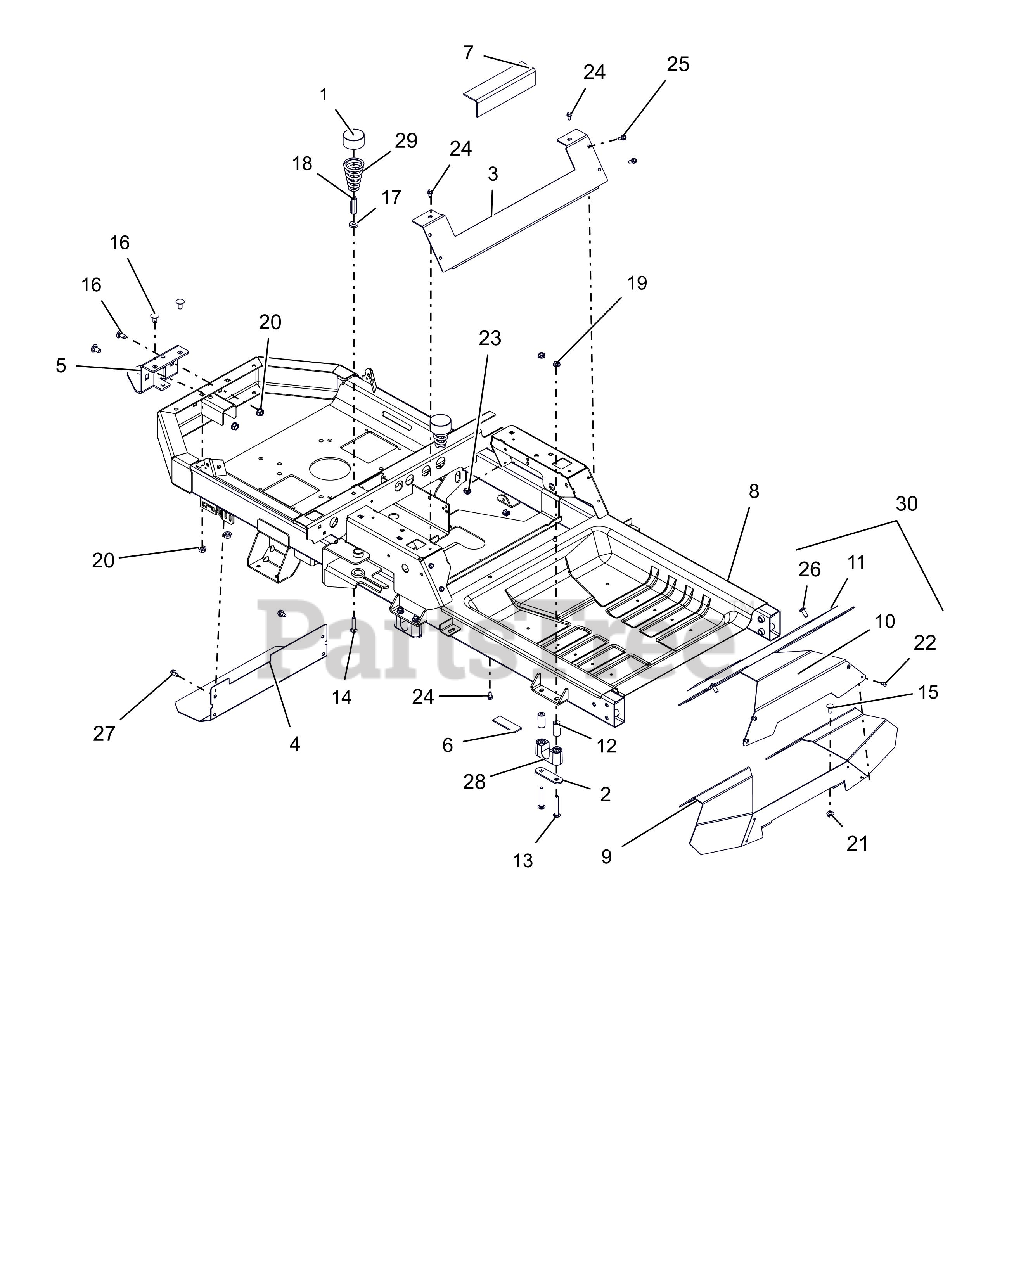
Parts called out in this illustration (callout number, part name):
1	HUB CAP
2	PLATE, BEARING SUPPORT
3	PLATE, SEAT KICK
4	HEAT, SHIELD
5	BRKT, HITCH TONGUE
6	PAD,RBR 1.0"X3.0" W/ADHESIVE
7	PAD, RUBBER-TANK
8	WLDMT, FRAME -IKON X/XL ARIENS
9	PLATE,FOOT
10	PLATE,FOOT
11	GRIP TAPE, FOOT PLATE
12	SPACER, .323 X .698 X 1.441
13	BLT-RDHDSQSHNK .31-18X2.25 YWZ
14	@BLT-RDHDSQNK .31-18X1.50 G5YZ
15	@BLT-RDHDSQNK .31-18X.75 G5YZ
16	@BLT-RDHDSQNK .38-16X.75 G5YZ
17	WSHR-FL-STL .328X.87X.179 YWZC
18	NUT, COUPLING 5/16-18 X 1 3/4
19	@NUT-LK-CTR-FLG .31-18 YZ GR F
20	@NUT-LK-TOP-FLG .38-16 YWZC
21	@NUT-LK-TOP-FLG .31-18 YWZC
22	RIVET, #66 STEEL POP PD BLACK
23	NUT RETNR .25-20
24	SCR-TAP .25-20X.50 HWH TR YWZ
25	SCR-TAP-PM .25-20X.75 TR YWZ
26	SCR-RDHDSKTAP .31-18 X .75
27	@SCR-TAP .31-18X.50 HWH TR YWZ
28	BSHG, DECK LIFT PIVOT
29	SPRING, SEAT
30	KIT, IKON FOOT REST W/DECAL
